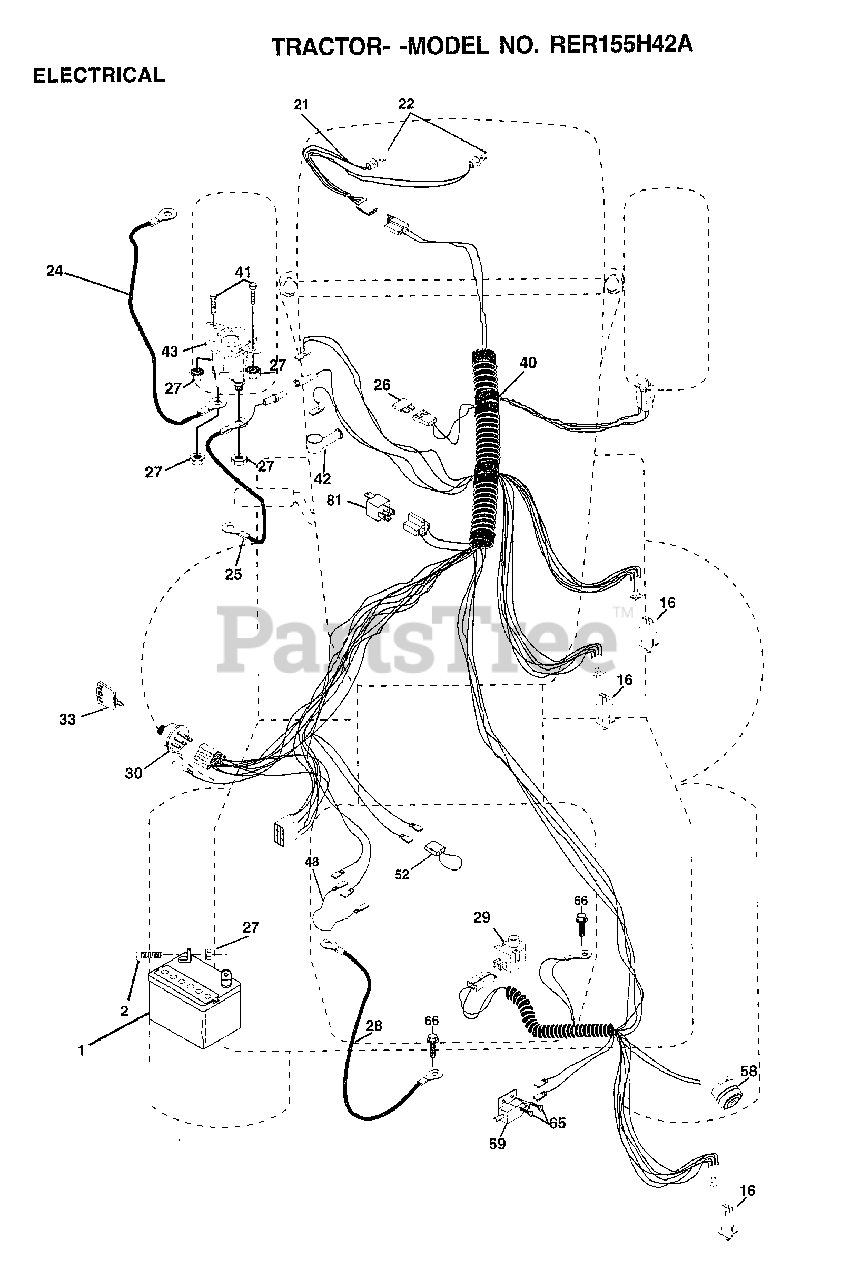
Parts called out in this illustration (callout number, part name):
2	BOLT LT
16	SWITCH INTERLOCK
21	HARNESS.ASM.LIGHT W/4152J
22	HEADLAMP BULB
24	"CABLE T, BATTERY"
25	CABLE.BATTERY.CRD
26	FUSE.15 AMP
27	NUT
28	"CABLE.GRD.6GA/18""BLACK"
29	SWITCH.PLUNGER
30	SWITCH.IGN.
33	KEY MLD GEN DELTA
40	HARNESS IGN CORD
41	BOLT HXHD FIN
48	ADAPTER AMMETER
52	PROTECTION LOOP
58	BUZZER CRD
59	SWITCH.FBI.CRD
65	SCREW
66	SCREW LT
81	RELAY ASSY T
